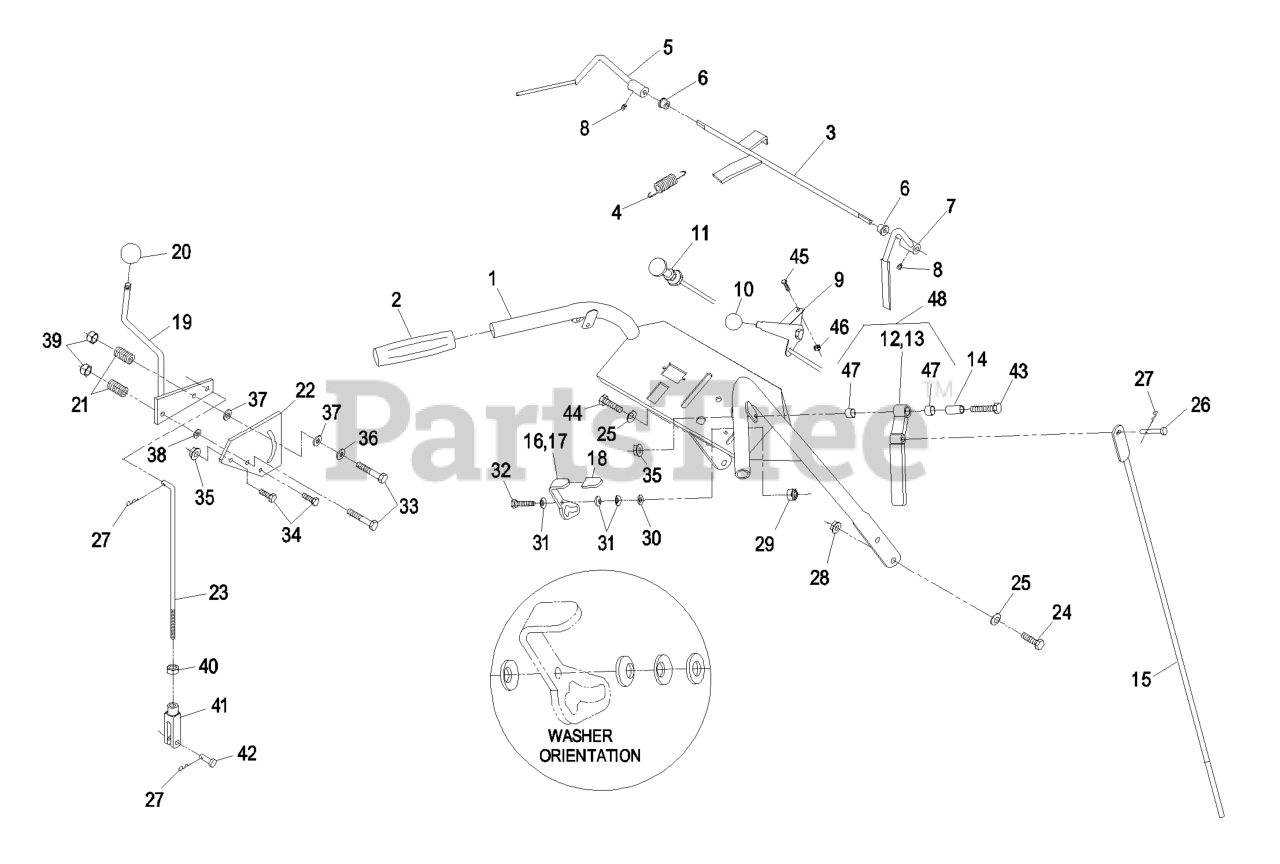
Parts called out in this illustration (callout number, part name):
3	WLD,ROD OPC
4	SPRING-EXTENSION
5	LEVER-LH
6	BUSHING-NYLON
7	LEVER-RH
8	SCREW-SET
9	THROTTLE CABLE ASM
10	KNOB-BALL
11	CONTROL-CHOKE, PUSH / PUL
12	RH DRIVE LEVER ASM
14	BUSHING-LEVER, DRIVE
15	ROD,DRIVE LEVER
18	GRIP-LATCH
19	LEVER-SHIFT
20	KNOB-BALL
21	SPRING-COMPRESSION
22	PLATE-LEVER, SHIFTER
23	ROD,SPEED CONTROL
24	SCREW-HH
25	WASHER-BELLEVILLE
26	PIN-CLEVIS
27	PIN-COTTER
28	NUT-HHF, WHIZ
29	NUT-LOCK, NI
30	WASHER-FLAT
31	WASHER-SPRING
32	SCREW-HH
33	SCREW-HH
34	SCREW-HH
36	WASHER-FRICTION
37	WASHER-FRICTION
38	WASHER-PLAIN
39	NUT-LOCK, NI
40	NUT-JAM
41	YOKE-ADJUSTABLE
42	PIN-CLEVIS
43	SCREW-HH
44	SCREW-HH
45	BOLT-CARR
46	NUT-LOCK, NI
47	BUSHING-SLEEVE
48	RH DRIVE LEVER ASM
